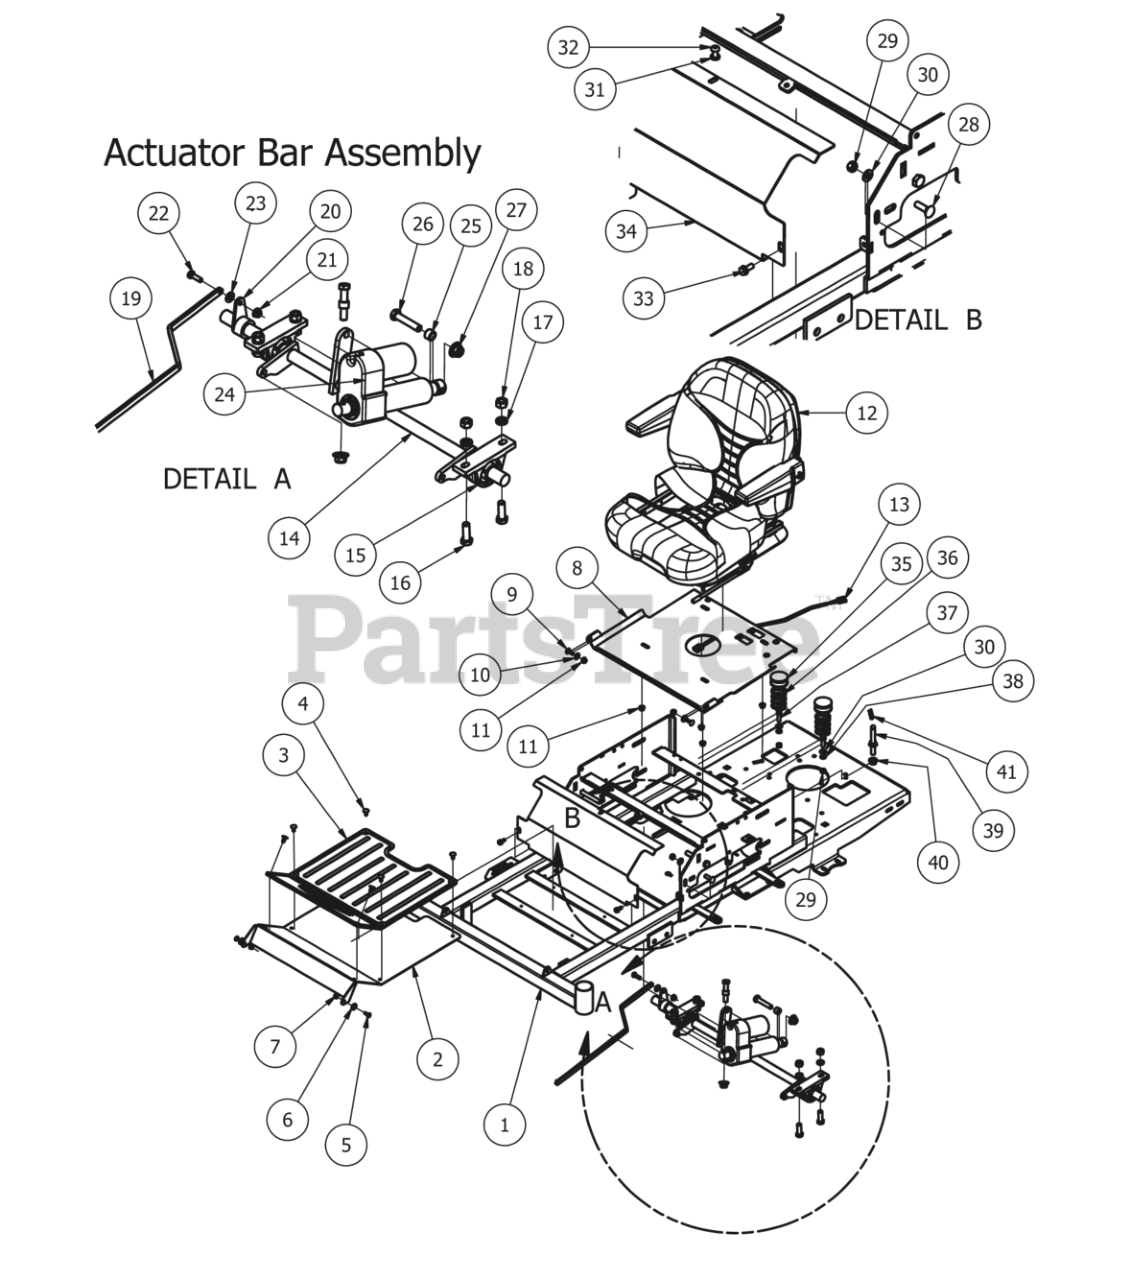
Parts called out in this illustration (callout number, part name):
2	ZT Floor Panel
3	Zt Floorboard Mat
4	Ratchet Fastener
5	1/4" x 3/4" Carriage Bolt
6	.360 ID Plastic Washer
7	1/4" Nylock Nut
8	ZT Seat Plate
9	5/16" x 7/8" Carriage Bolt
10	.360 ID Plastic Washer
11	5/16" Flange Nut Zinc W/Serrations
12	ZT/Pup Seat - WM1976
13	Seat Switch Adapter
14	Actuator Bar
15	Pillow Block Bearing
16	1/2" x 1 1/2" Hex Bolt
17	1/2" Lock Washer
18	1/2" Hex Nut
19	Height Indicator Bar
20	Height Indicator Lever
21	5/16" Flange Nut Zinc W/Serrations
22	5/16" x 1" Bolt
23	.360 ID Plastic Washer
25	1/2 x 1/2 Spacer
26	1/2" x 2 1/2" Hex Bolt
27	1/2-13 Nylon Flange Nut-Orange
28	3/8" x 1 1/4" Carriage Bolt
29	3/8" Hex Nut
30	3/8" Flat Washer
31	5/16" Lock Washer
32	5/16" x 3/4" Button Head Bolt
33	5/16 x 3/4 washer head type F screw
34	ZT Cooler Cover 2010 & Up
35	Spring Cap Cover
36	Seat Spring
37	3/8" x 1 1/4" Hex Bolt
38	3/8" Lock Washer
39	Seat Braket Pin
40	1/2" Flange Nut
41	Seat latch pin
